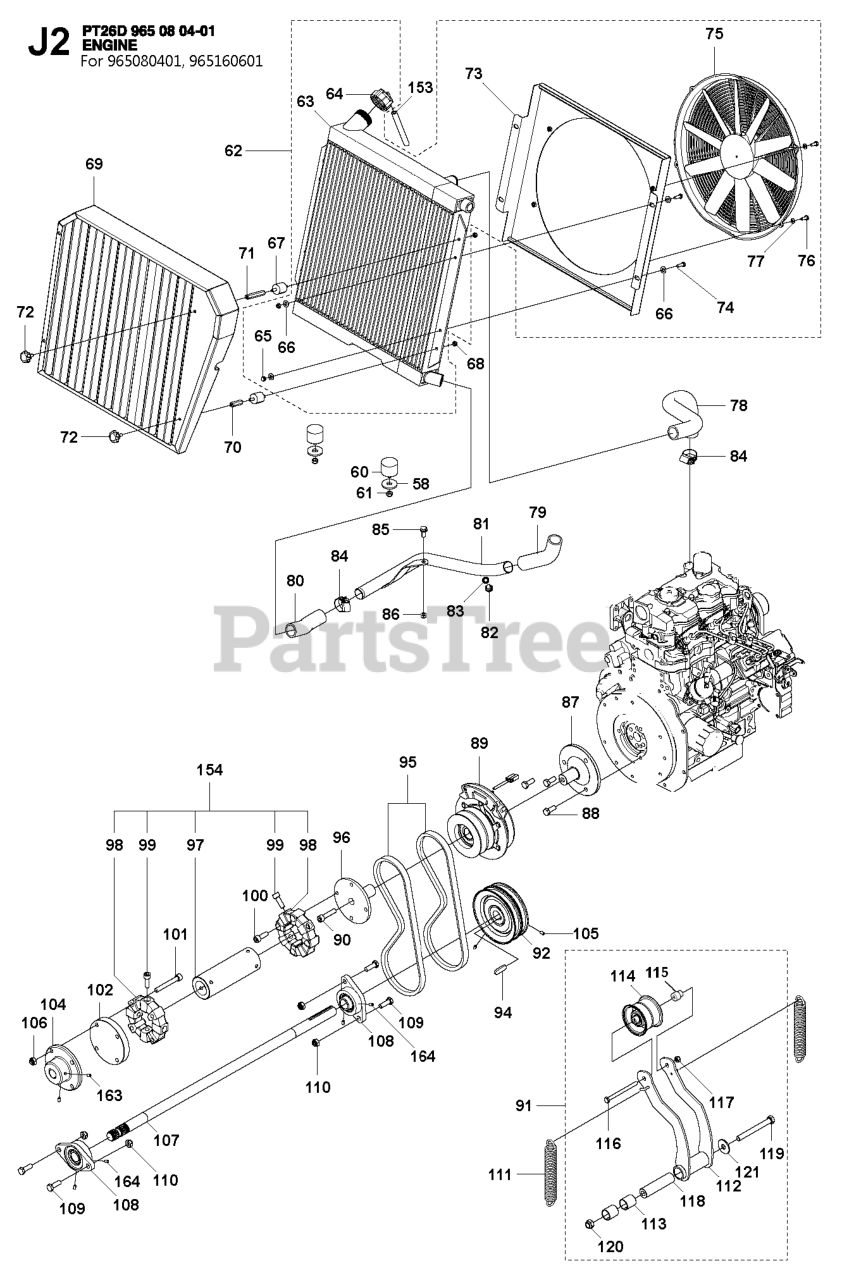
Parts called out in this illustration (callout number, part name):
60	ANTIVIBRATION ELEMENT
61	LOCKNUT M8
62	RADIATOR ASSY
65	LOCKNUT M6
66	WASHER - 15X7.3X1.6
67	ANTIVIBRATION ELEMENT RADIATOR
68	LOCKNUT M6
75	ELECTRIC FAN
76	Screw
77	WASHER - M6
78	HOSE COOLING WATER
79	HOSE COOLING WATER
80	HOSE COOLING WATER
81	TUBE COOLING WATER
82	SCREW EHHM
86	LOCKNUT M8
87	POWER TAKE OFF
88	Screw M10x25
95	BELT PTO DOUBLE
97	SHAFT CLUTCH SHORT
98	RUBBER RING CLUTCH
100	SCREW IHSCM M10X30 12.9 ZPB L
101	SCREW IHSCM 10X75 12.9 ZPB
106	NUT
108	BEARING UNIT FYTB 25TF
111	DRAW SPRING L=85,8
113	BUSHING
117	NUT
118	SLEEVE 96.5MM
